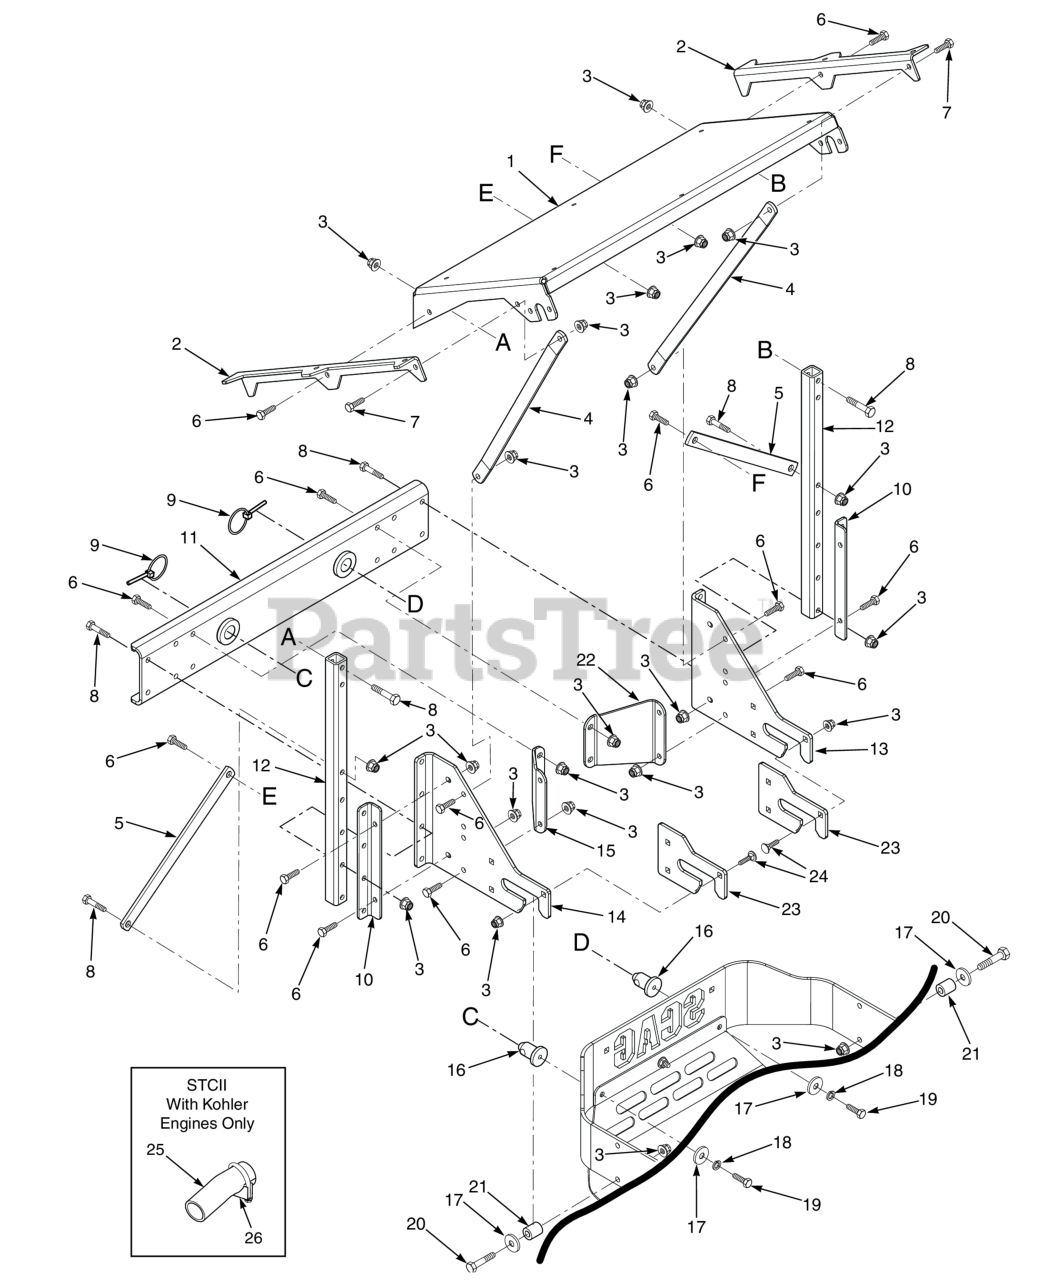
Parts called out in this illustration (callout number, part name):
1	Support Frame, Hopper
2	Bracket, Hopper Support
3	Nut, Flange Elastic Stop Nut, 3/8-16
4	Brace, Stiffener
5	Brace, Engine Mounting
6	Bolt, Hex Head, 3/8-16 x 1 Gr. 5
7	Bolt, Hex Head 3/8-16 x 1-1/4" Grade 8
8	Bolt, Hex Head 3/8-16 x 2-1/4" - 61"
9	Quick Pin, 5/16" Dia.
10	Mounting Bracket, Tube
11	Mounting Bracket Weldment
12	Tube, Upright
13	Mounting Bracket, GC R.H.
14	Mounting Bracket, GC L.H.
15	Angle Bracket, GC
16	Pin, GC Locator
17	Flatwasher, 3/8-.406 x 1-1-1/2 x 7 Gauge
18	Lockwasher, 3/8" Spring, Kawasaki FX / FT & FT-EFI / B&S 32BV
19	Bolt, Hex Head 3/8-16 x 1-1/4" Grade 8
20	Bolt, Hex Head 3/8-16 x 2-1/4" - 61"
21	Spacer
22	Angle Bracket, GC
23	Wear Plate, GC
24	Carriage Bolt, 3/8-16 x 1-1/4"
25	TUBE, EXHAUST
26	Clamp, Muffler (Clamp Only)
